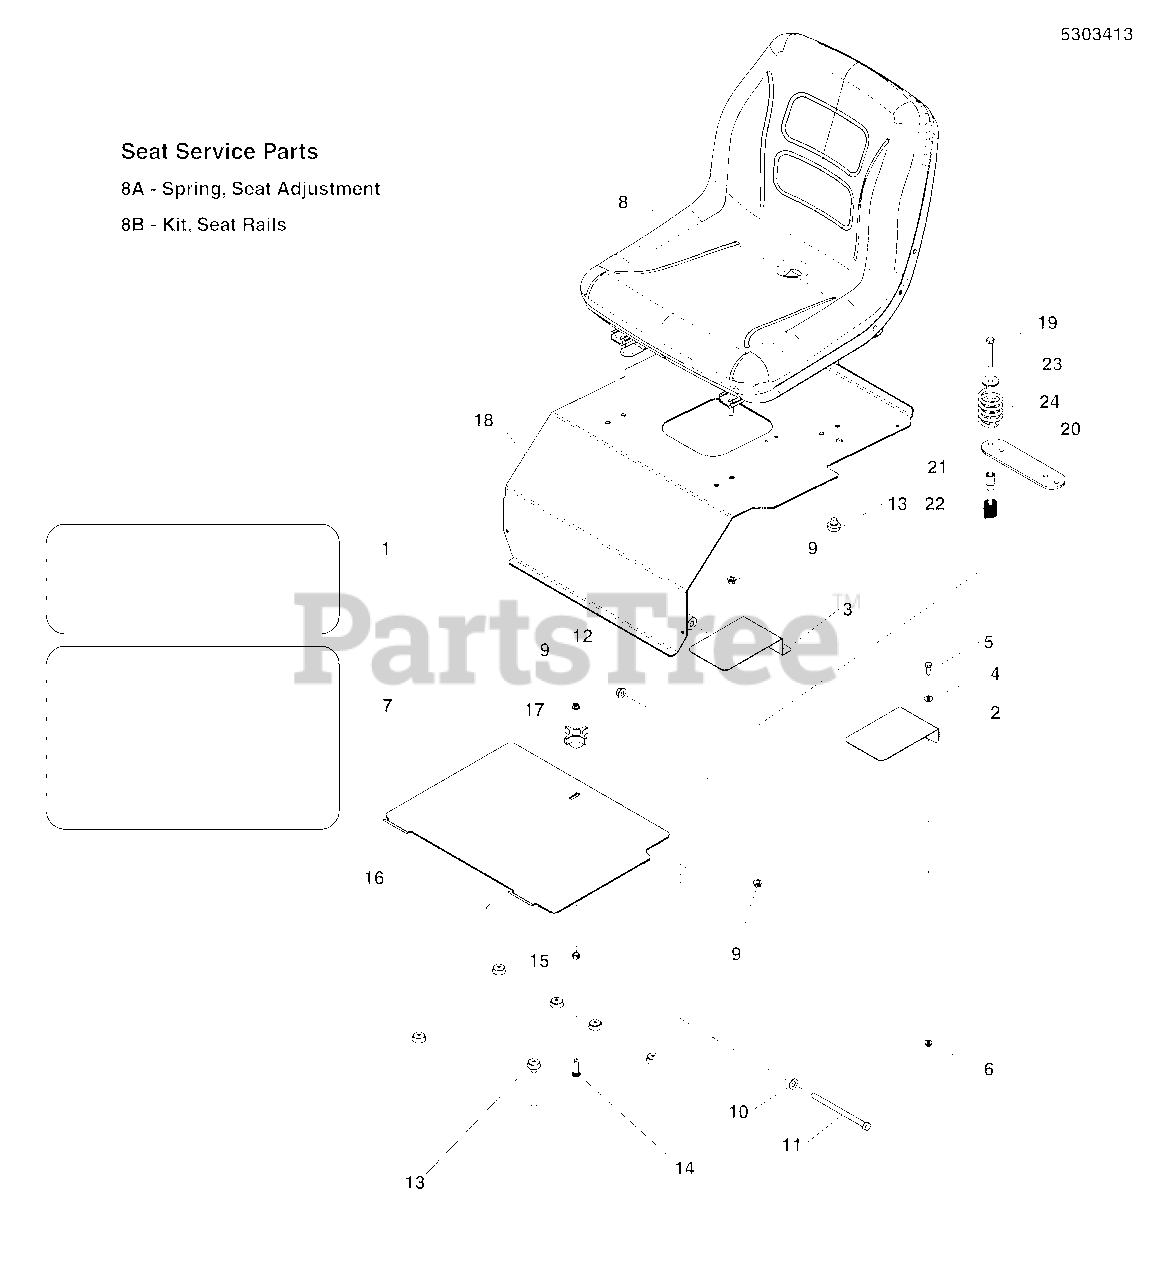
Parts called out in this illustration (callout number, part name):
1	SAFETY WALK, FLOOR REST, 6.00 X 16.00
2	PLATE, FAN GUARD, LH - BLK
3	PLATE, FAN GUARD, RH - BLK
4	WASHER, Flat, 1/4
5	BOLT, 1/4-20 X 3/4 GD5 YZ
6	NUT, Nylock Flanged, 1/4-20
7	SAFETY WALK, FLOOR PLATE, 16.00 X 10.00
8	SEAT, NO ARM REST
8A	SPRING, Extension, Seat Adjustment (BLK or SLVR) (3-1/2" Total unstretched length.)
8B	SEAT RAIL, KIT, RH AND LH (SV)
9	NUT, 5/16-18 HEX NYLOCK FLANGE
10	WASHER, 3/8 SAE
11	BOLT, 3/8-16 X 5-1/2 GD5 CZ
12	NUT, Hex Flange, Nylock, 3/8-16
13	MNT, VBRTN, RBBR
14	BOLT, 5/16-18 X 1-1/4, CARRIAGE YZ
15	NUT, 5/16-18, HEX, CNTR LK,ZINC PHOS/OIL (80003675)
16	PLATE, FLOOR, REMOVABLE - RED
17	KNOB-INT THR .312-18 4-ARM 2.12WD 1.06LG
18	ASSM, SEAT PLATE W/DECALS - 550Z
18	ASSM, SEAT PLATE W/ DECALS, 550Z ANSI-EXP
19	BOLT, 5/16-18 X 2-1/4 GD5 YZ
20	PLATE, SEAT SWITCH, RED
21	SPACER, .33 X .66 X 1.31 SHLDR, CZ
22	SPRING, COM 720ID X 1.31KG X .118WIRE
23	WASHER, .34 X 1.25 X 10 GA
24	SPRING, SEAT SUPPORT
